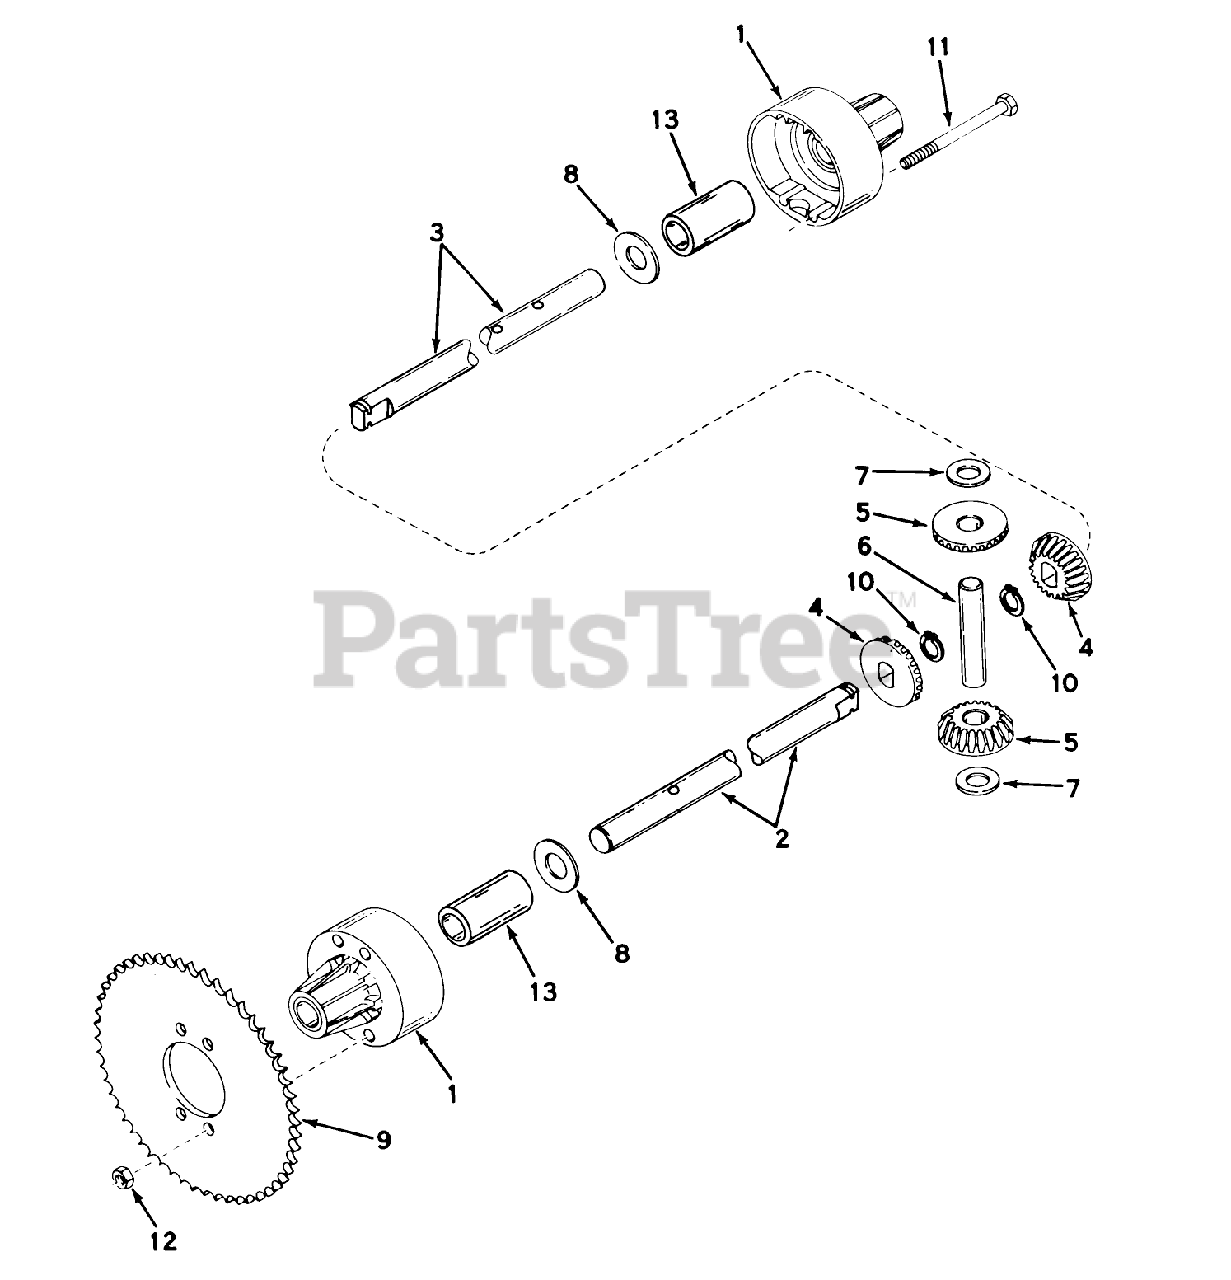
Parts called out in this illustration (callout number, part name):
1	Housing, Differential Carrier
2	Axle (827/32" long)
3	Axle (13 23/32" long)
4	Bevel Gear
5	Gear Pinion
6	Pin Drive
7	Washer, Thrust
8	Washer
9	Sprocket (40 teeth)
10	Snap Ring
11	Screw-Hex Hd.
12	Nut-Lock
13	Bushing
